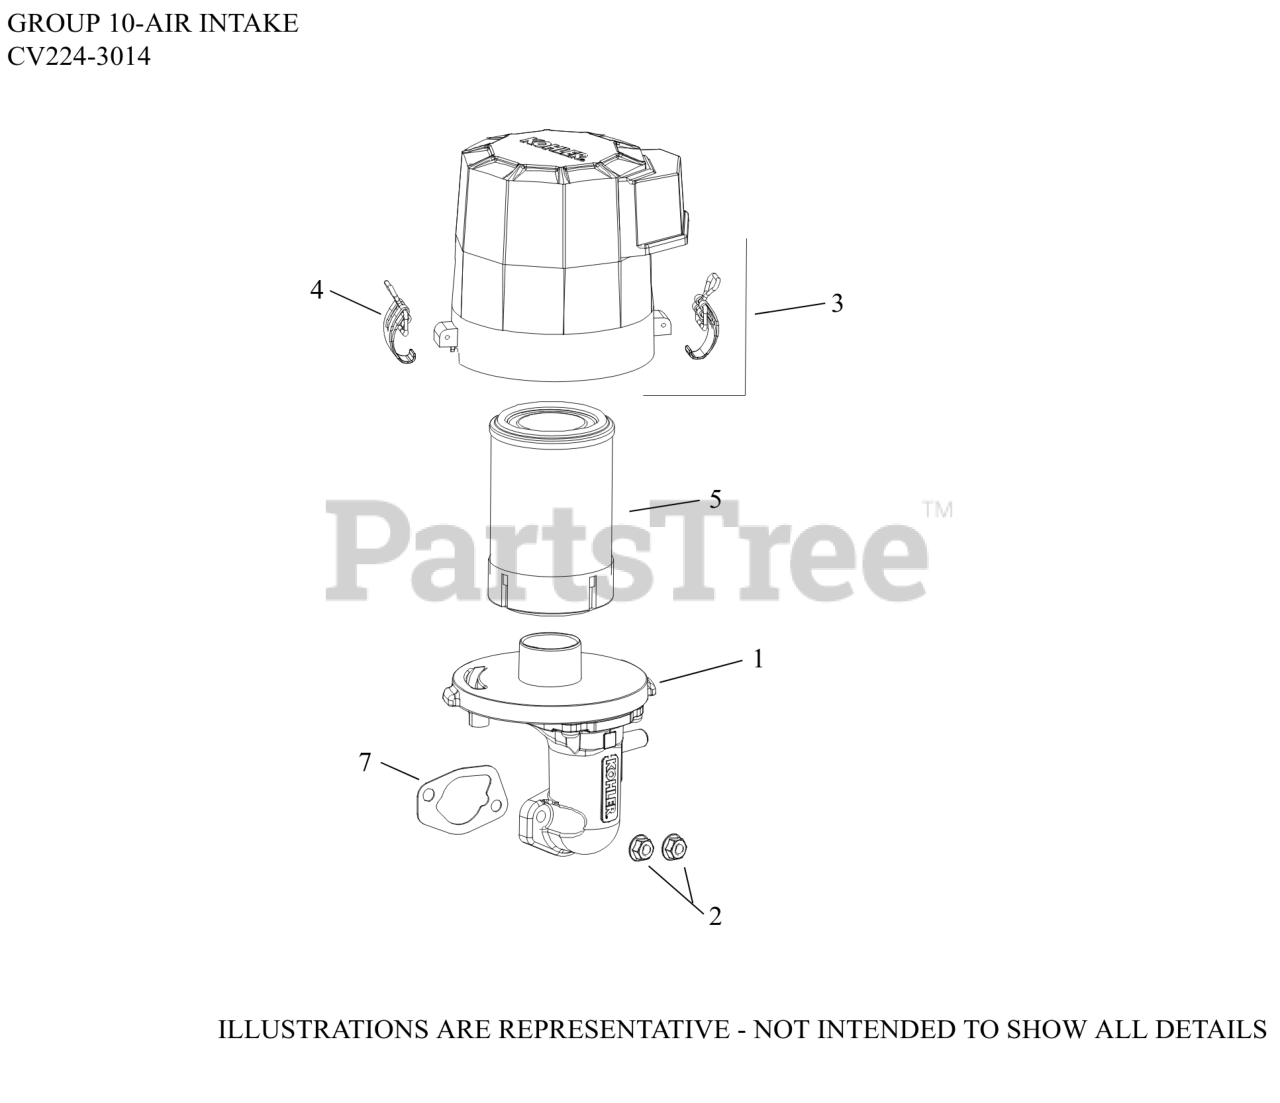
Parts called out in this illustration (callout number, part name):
1	BASE, AIR CLEANER CYCLONIC ASSEMBLY
2	NUT, HEX FLANGE LOCK (M6)
3	COVER, AIR CLEANER ASSEMBLY
4	KIT, LATCH CLIP
5	ELEMENT, AIR FILTER
7	GASKET, AIR CLEANER BASE
